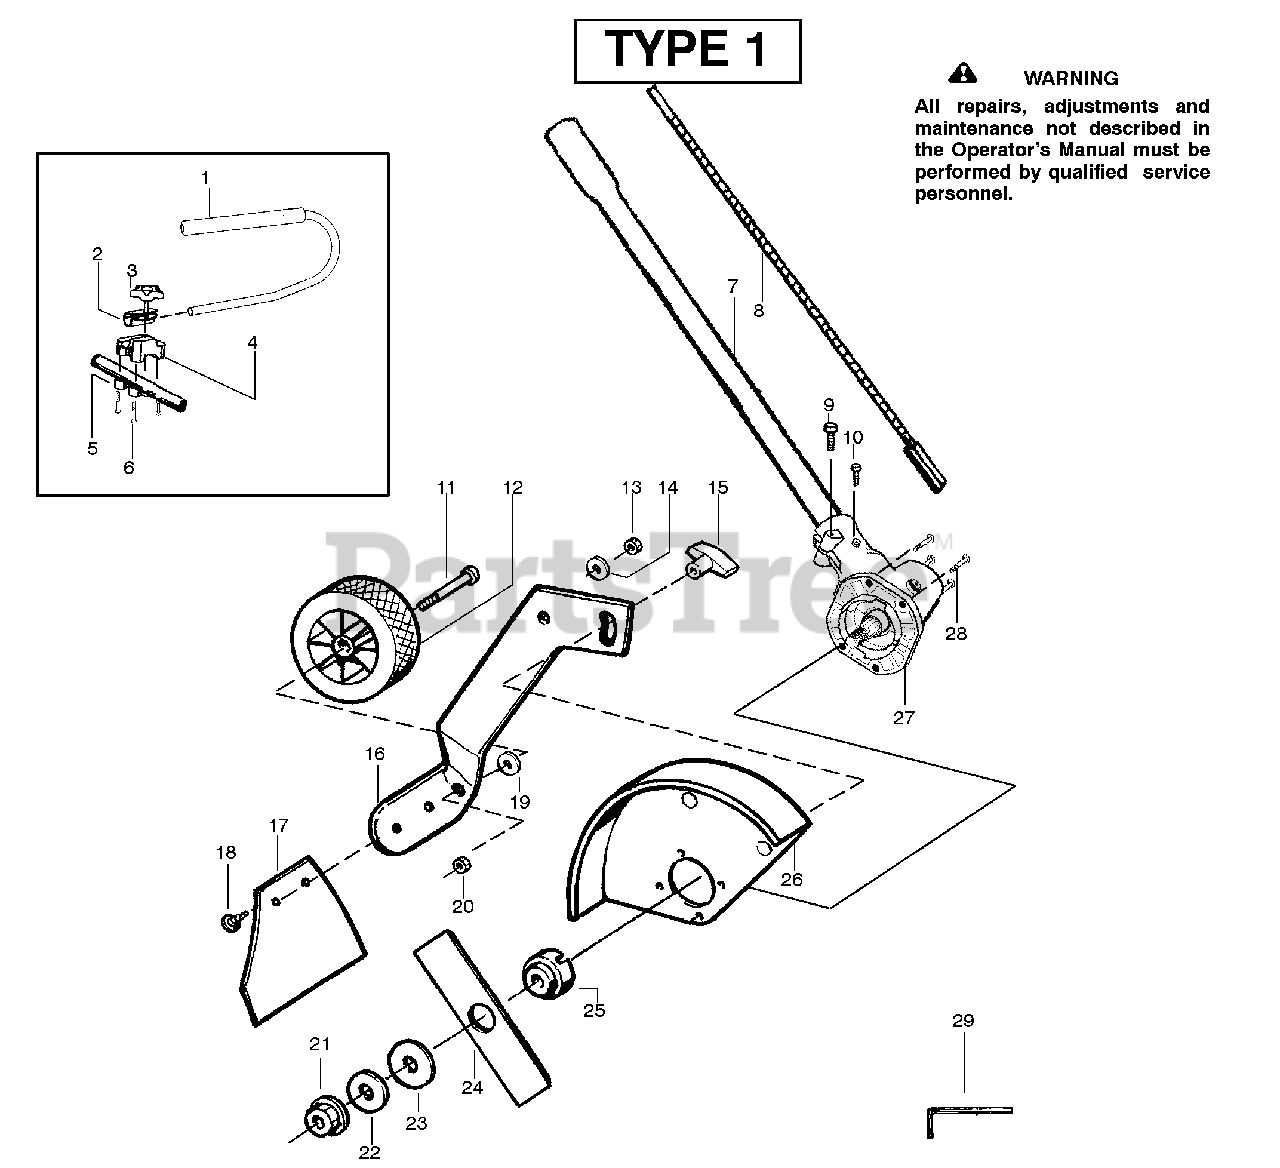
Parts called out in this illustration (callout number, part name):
1	Kit - Handlebar
2	Clamp - Handlebar
3	Knob
4	Base - Clamp
5	Kit - Clamp - Tube
7	Assy. - Driveshaft
8	Flexshaft - Split boom
10	Screw - Alignment
11	Bolt - Shoulder Axle
12	Wheel - 4"
16	Bracket - Adj. Wheel
17	Kit - Mud Flap
18	Fastener - Mud Flap
21	Nut - Flange
22	Washer - Belleville
23	Washer - Flat
26	Kit - Edger Guard
27	Kit - Gearbox
29	Wrench - Hex
